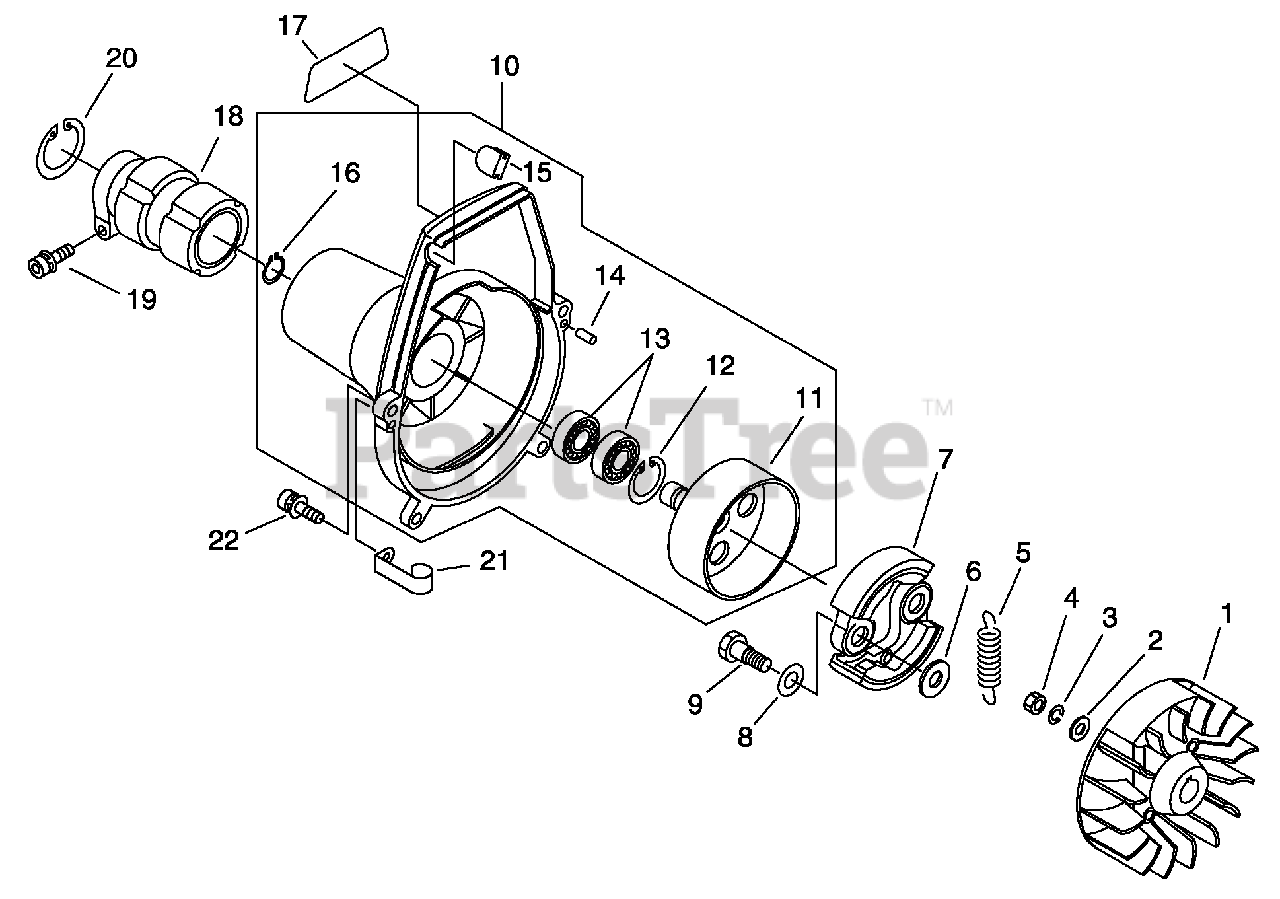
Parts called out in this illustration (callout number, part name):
1	FLYWHEEL
2	WASHER - 8
3	LOCKWASHER - 8
5	SPRING, CLUTCH
6	WASHER - 6
7	SHOE, CLUTCH
8	WASHER - SPRING
9	BOLT, CLUTCH
10	FAN CASE ASSY
11	DRUM, CLUTCH
12	RING, RETAINING - 26
13	BEARING, BALL - 6000LU
14	PIN - LOCATING
16	RING, RETAINING - 10
17	LABEL - MODEL SRM-270
18	CLAMP, MAIN PIPE
19	SCREW - 5X28
20	RING, RETAINING - 42
22	SCREW - 5X18
